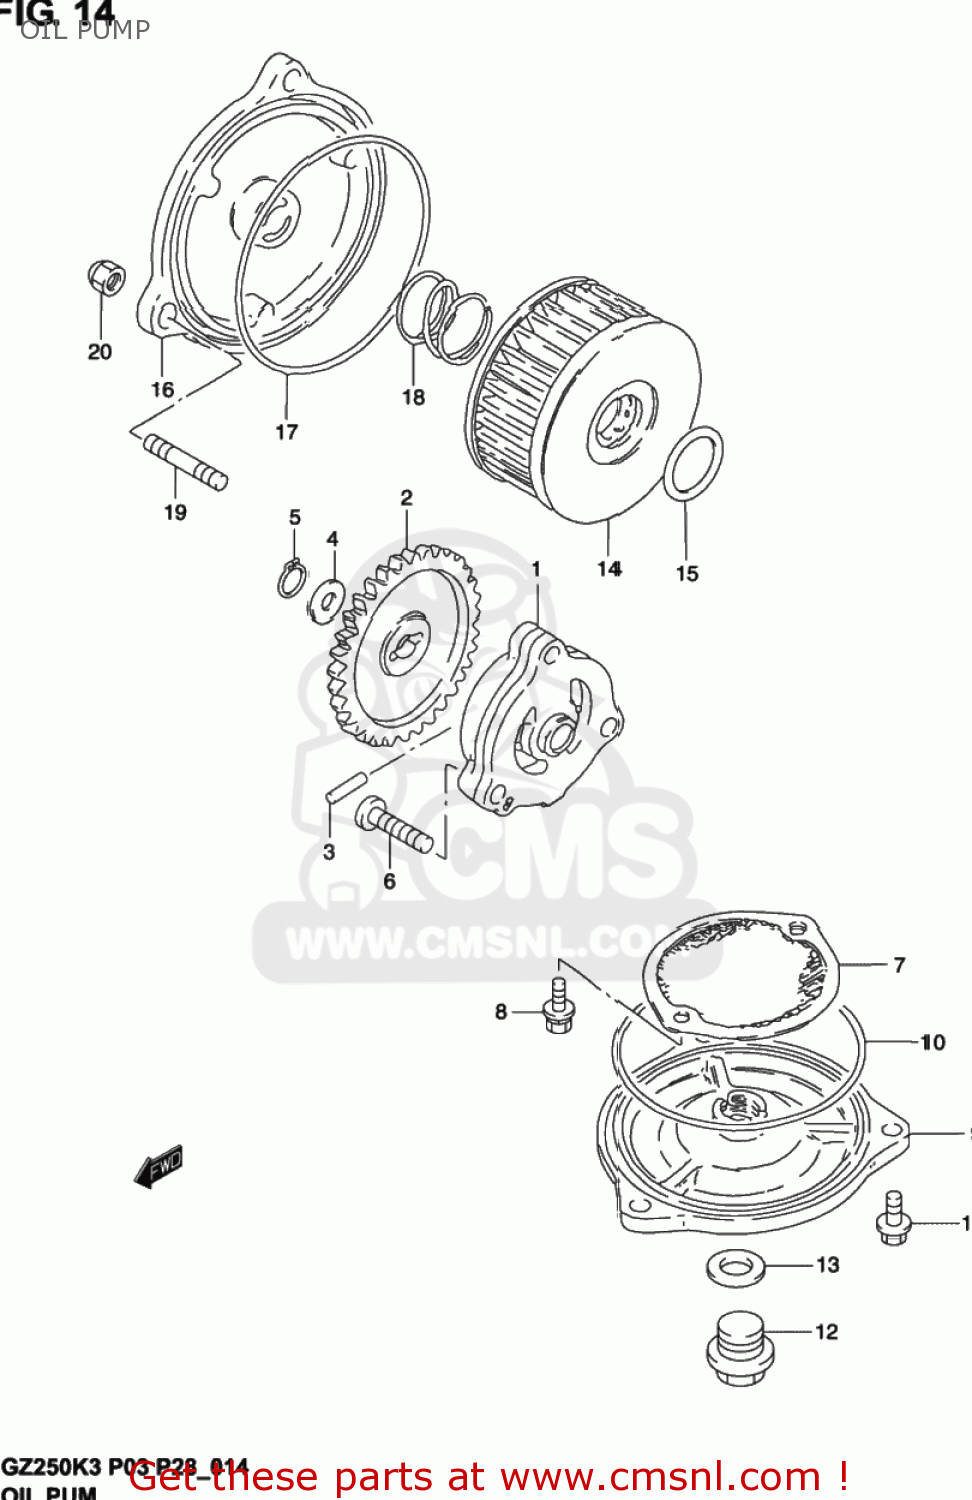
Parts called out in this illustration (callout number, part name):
1	PUMP ASSY,ENGINE OIL
2	GEAR,OIL PUMP DRIVEN(NT:33)
3	PIN(4X15.8)
4	SHIM(10X18X0.5)
5	CIRCLIP,10MM
6	SCREW
7	STRAINER,ENGINE OIL
8	SCREW
9	CAP,OIL STRAINER
10	O RING(D:2.4,ID:85)
11	SCREW
12	PLUG(14X12)
13	GASKET(13.8X18.8X4.8) (NAS)
14	FILTER ASSY,ENGINE OIL
15	O RING(D:2.4,ID:15.8)
16	CAP,OIL FILTER
17	O RING(D:2.4,ID:73)
18	SPRING
19	BOLT,STUD
20	NUT
